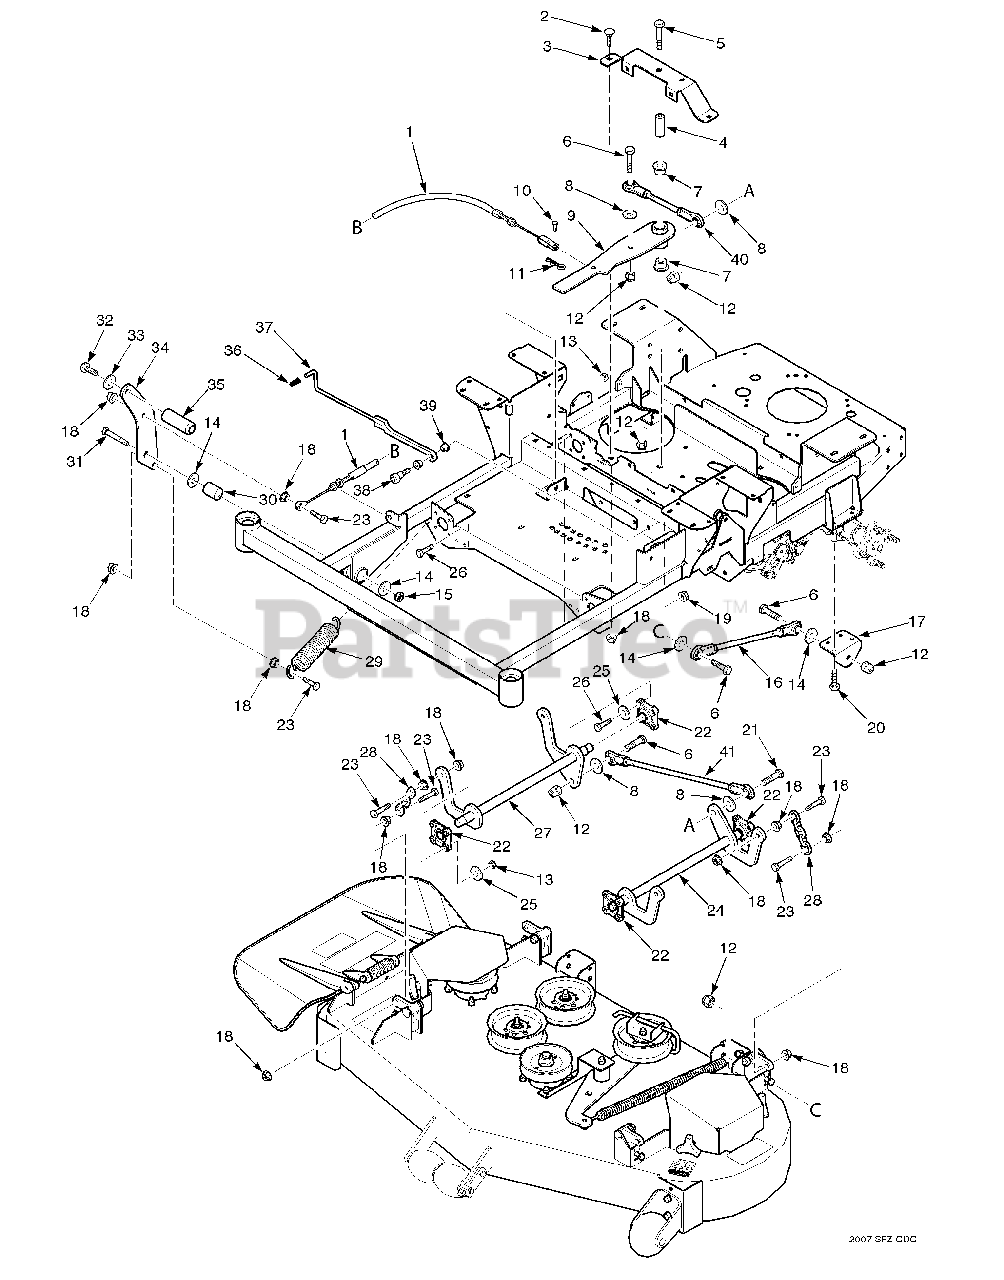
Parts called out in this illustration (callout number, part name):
1	Cable, Deck Lift
2	Bolt, Carriage 3/8-16 x 3/4"
3	Support, Idler Arm
4	Spacer, Deck Lift Pivot
5	Bolt, Hex Head 1/2-13 x 3-1/4"
6	Bolt, Hex Head 1/2-13 x 1-3/4"
7	Bearing
8	Flatwasher, 1/2-.531 x 1.06 x .095
9	Deck Lift Bellcrank Assy.
10	Clevis Pin, 5/16 x 3/4"
11	Hair Pin, .094 x 1.62"
12	Nut, Elastic Stop 1/2-13
13	Nut, Elastic Stop 5/16-18
14	Flatwasher, 1/2-.562 x 1.375 x .109
15	Nut, Center Lock 1/2-13
16	Linkage, Push Arm
17	Bracket, Push Arm Link
18	Nut, Serrated Flange 3/8-16
19	Nut, Elastic Stop 3/8-16
20	Bolt, Hex Head 5/16-18 x 3"
21	Bolt, Hex Head 1/2-13 x 2-1/2"
22	Bearing, Deck Lift
23	Bolt, Hex Head 3/8-16 x 1-1/2"
24	Weldment, Deck Lift LH
25	Flatwasher, 1/4-.312 x .750 x .065
26	Bolt, Hex Head 5/16-18 x 1"
27	Weldment, Deck Lift RH
28	Chain, Deck Lift
29	Spring, Deck Lift
30	Sleeve, Deck Lift Pivot
31	Bolt, Hex Head 1/2-13 x 3"
32	Bolt, Hex Socket 5/8-11 x 1-1/2"
33	Lockwasher, 5/8" Spring
34	Pedal, Foot Bracket
35	Foot Pedal
36	Grip, Deck Latch
37	Weldment, Deck Latch
38	Bolt, Shoulder 1/2 x 1/2"
39	Bearing
40	Linkage Assy., Deck Lift
41	Linkage Assy., Deck Lift
